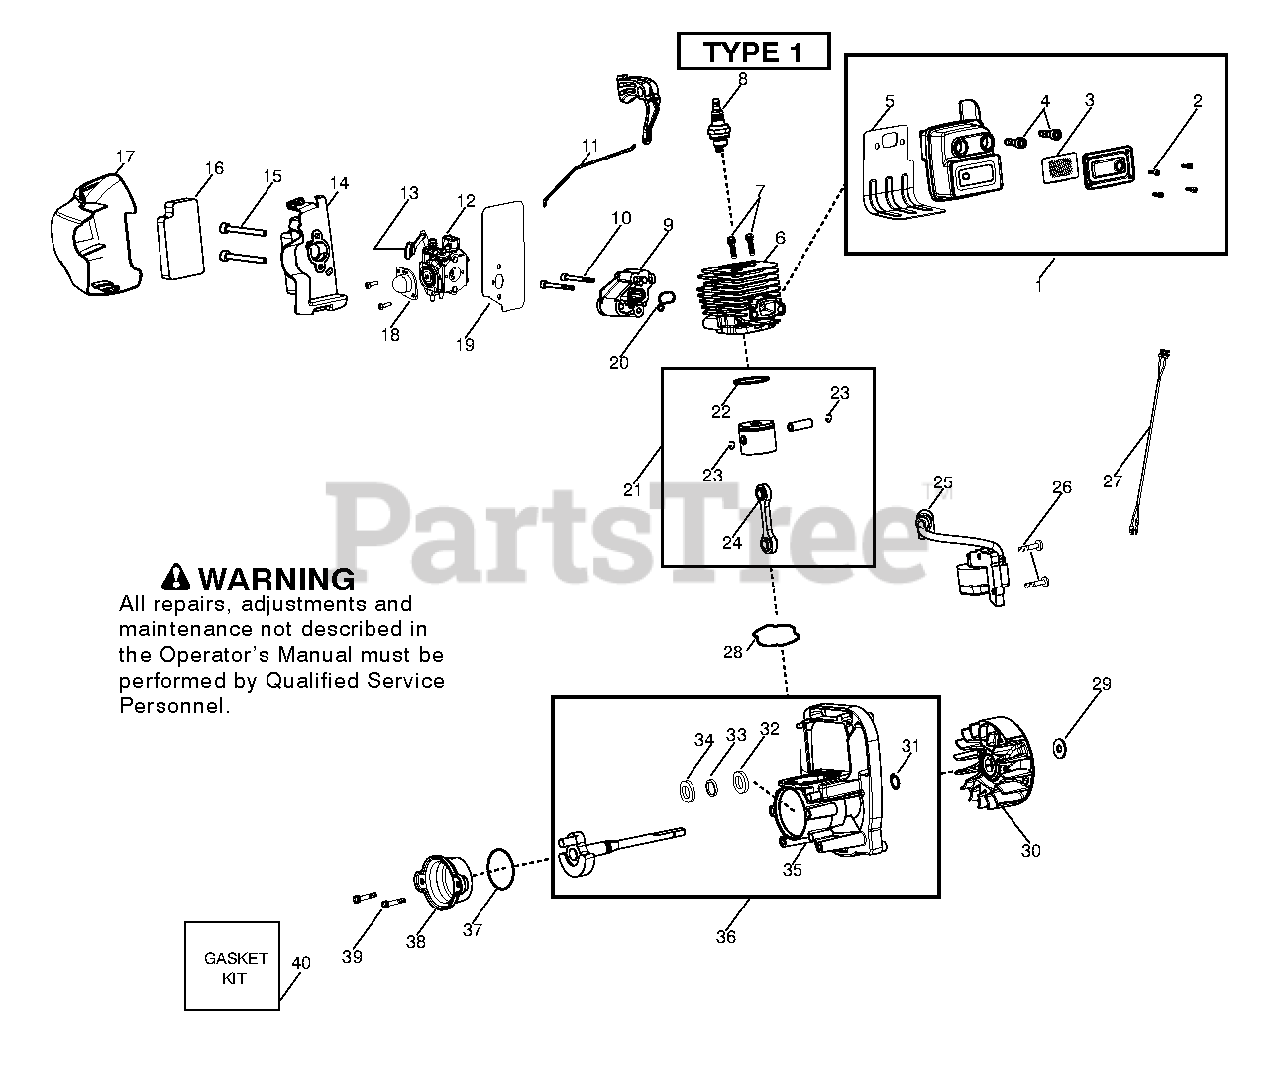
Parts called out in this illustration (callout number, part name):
1	ASSY MUFFLER
2	SCREW-6-19X5/16PLAST PA
3	Muffler Assembly, Welded
5	KIT GASKET 25CC
6	CYLINDER CHROME 25CC
8	PLUG-SPARK (RCJ-6Y)
9	ADAPTER CARBURETOR
11	LINKAGE THROTTLE
12	Carburetor Kit, C1U-W43
13	Choke Lever, C1U-W43
14	BASE AIRBOX PP GOLD
16	Air Filter, Foam
17	Air Box Cover, Black
18	PURGE BULB ZAMA
19	KIT GASKET 25CC
20	KIT GASKET 25CC
21	KIT PISTON CONN ROD
22	RING-PISTON
23	WRIST PIN RET.
24	KIT PISTON CONN ROD FORGED
25	KIT MODULE W/0 INTERRUPT
28	KIT GASKET 25CC
30	FLYWHEEL
31	RETAINING RING
32	OUTER BEARING
34	BEARING
35	ASSY CRANKCASE
36	ASSY CRANKCASE & CRANKSHAFT
37	KIT GASKET 25CC
38	ASSY REAR PLUG
40	KIT GASKET 25CC
